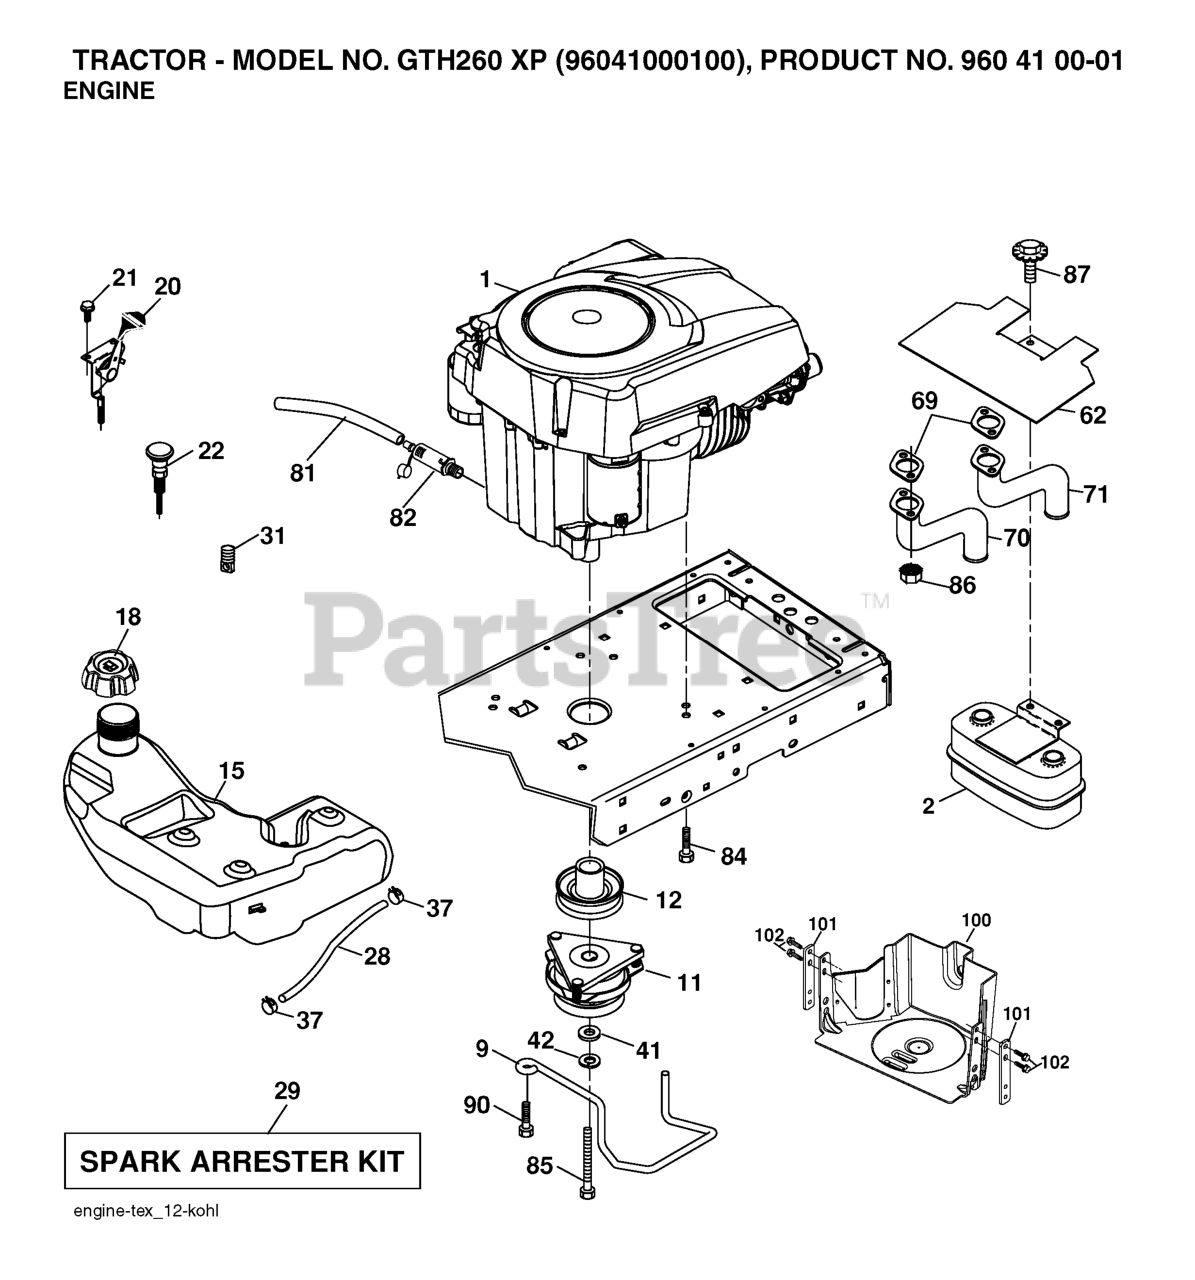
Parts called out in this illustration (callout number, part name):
2	MUFFLER.TWIN.CYL.LOW.TONE
9	KEEPER.BELT.ENGINE.4.2
11	CLUTCH MZ ZTR GT.48/54"1.125"
12	PULLEY ENGINE
15	TANK.FUEL.4GAL
18	CAP.FUEL.TANK.3"GREY
20	THROTTLE CONTROL
21	SCREW
22	CONTROL.CHOKE.ERGO.PUSH-IN.BLA
28	FUEL LINE 54"
29	KIT.SPARK ARRESTOR 794945 B&S
37	HOSE CLAMP
42	LOCKWASHER
62	RP SHIELD HEAT MUFFLER
70	RP.PIPE-EXHAUST LH
71	RP.PIPE-EXHAUST RH
80	FLANGE NUT
81	TUBE, DRAIN OIL ASM.
82	PLUG DRAIN OIL EASY
84	SCREW.3/8-16
85	BOLT HEX 7/16-20 X 3.75 GR. 5
86	NUT.HEX.FLANGE.TOPLOCK
87	BOLT.5/16-18UNCX1.W/SEMS.BLK
90	SCREW 3/8-16X1
91	BUSHING.1.375OD
96	CLIP RETAINER
100	GUARD ASM.ENGINE.48"TEX.RH.006
102	SCREW
103	WASHER, LOCK 3/8
104	NUT CROWNLOCK 3/8-24
